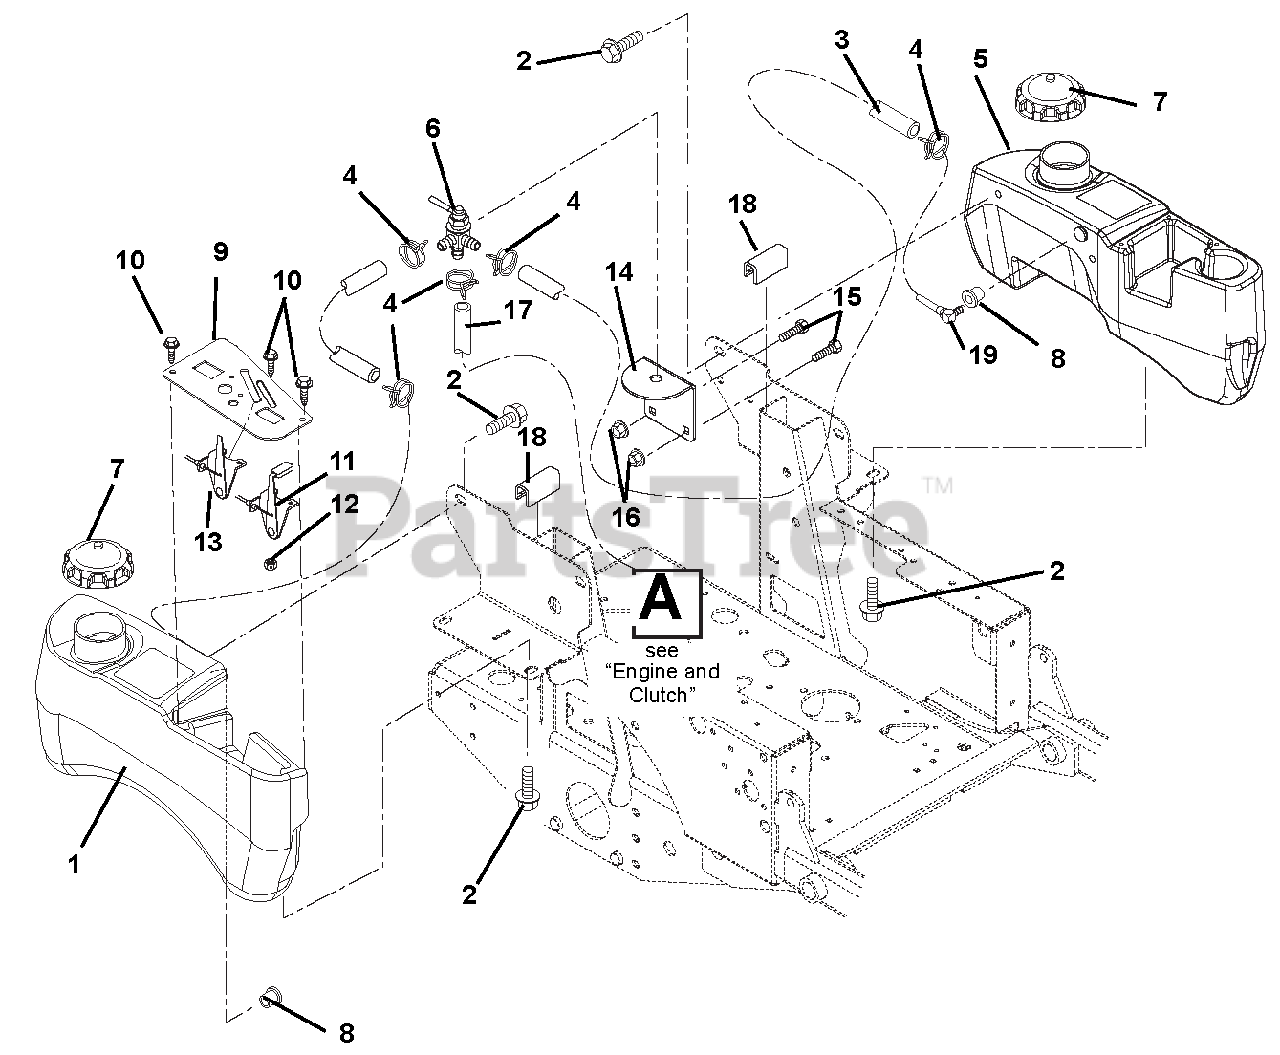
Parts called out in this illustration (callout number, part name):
1	TANK, FUEL RH W/O HOSE
2	BOLT, SEMS .31-18 X .62
3	HOSE, 5.75"-1/4" ID GAS LINE
4	CLAMP-HOSE WIRE .490/.510X.116
5	TANK, LH FUEL CZ W/O HOSE
6	VALVE, FUEL
7	CAP - FUEL
8	BSHG-FLG .375 X 1.062 X .625 R
9	PANEL, CONTROL
10	@SCR-MCH 10-24X.50 HWH YWZC
11	CABLE, THROTTLE-CHOKE
12	@NUT-LK-NYL 10-24 W/INSRT YWZC
13	CABLE, CHOKE
14	BRKT, FUEL VALVE MNTG
15	@BLT-RDHDSQNK .31-18X.75 G5YZ
16	@NUT-LK-NYL-FLG .31-18 YWZC
17	HOSE, 29"-1/4"ID GAS LINE
18	STRIP, COWL
19	ASS'Y, SMALL TANK FUEL PICK-UP
